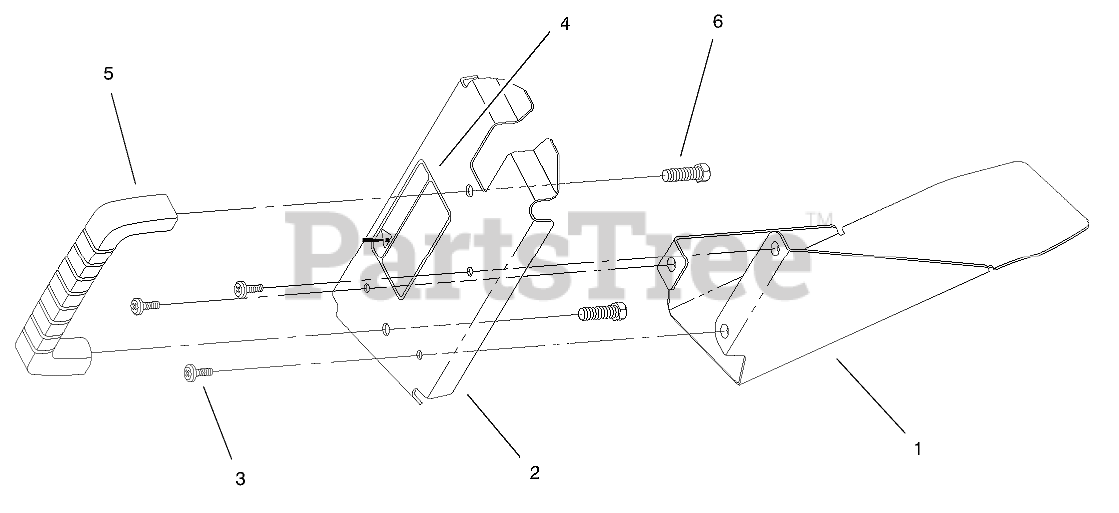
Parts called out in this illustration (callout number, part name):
1	Shield-Discharge Plug
2	Cover-Discharge Plug
4	DECAL - WARNING
5	HANDLE-DOOR
6	SCREW-HWH
